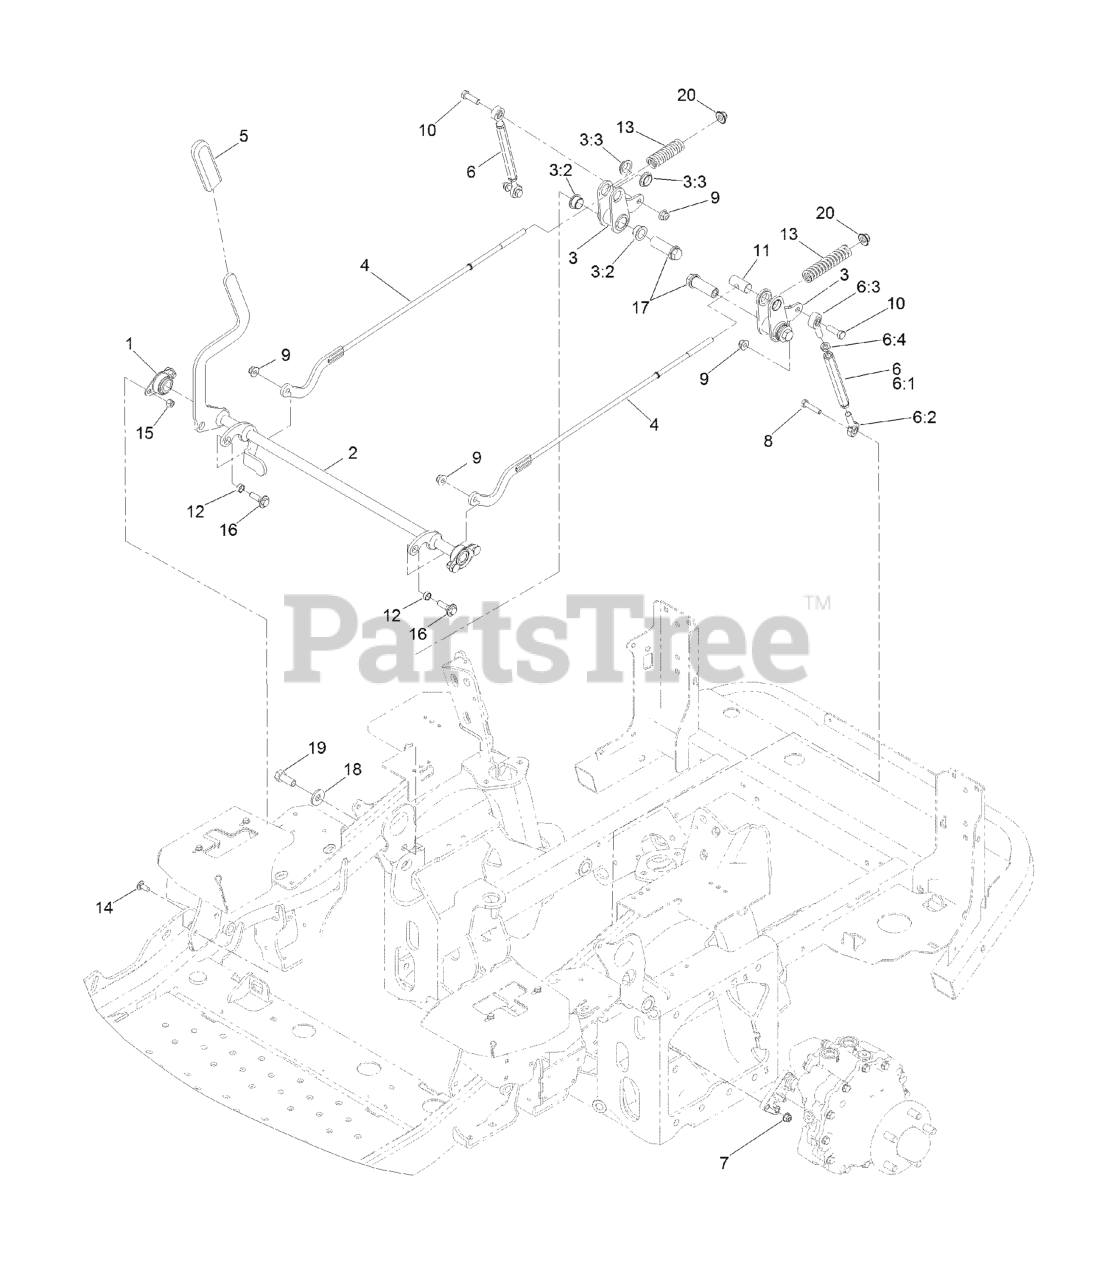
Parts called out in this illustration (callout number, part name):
1	BEARING-FLANGE, SIDE
2	SHAFT-BRAKE
3	BRAKE BELLCRANK ASM
3:2	BUSHING-FLANGE
3:3	BUSHING-FLANGE
4	LINK-BRAKE, UPPER
5	GRIP-LEVER
6	TURNBUCKLE ASM
6:1	TURNBUCKLE
6:2	BEARING-END, LH ROD
6:3	BALLJOINT
6:4	NUT-HJ
7	NUT-HF, NI
8	SCREW-HH
9	NUT-HF, NI
10	SCREW-HH
11	PIN-TRUNION
12	BEARING-SLEEVE
13	SPRING-COMPRESSION
14	SCREW-CARR
15	NUT-LOCK, NI
16	SCREW-SHOULDER, HWH
17	HUB-THREADED
18	WASHER-SPRING
19	SCREW-HH
20	Nut-Nyloc 3/8-16 Flg
